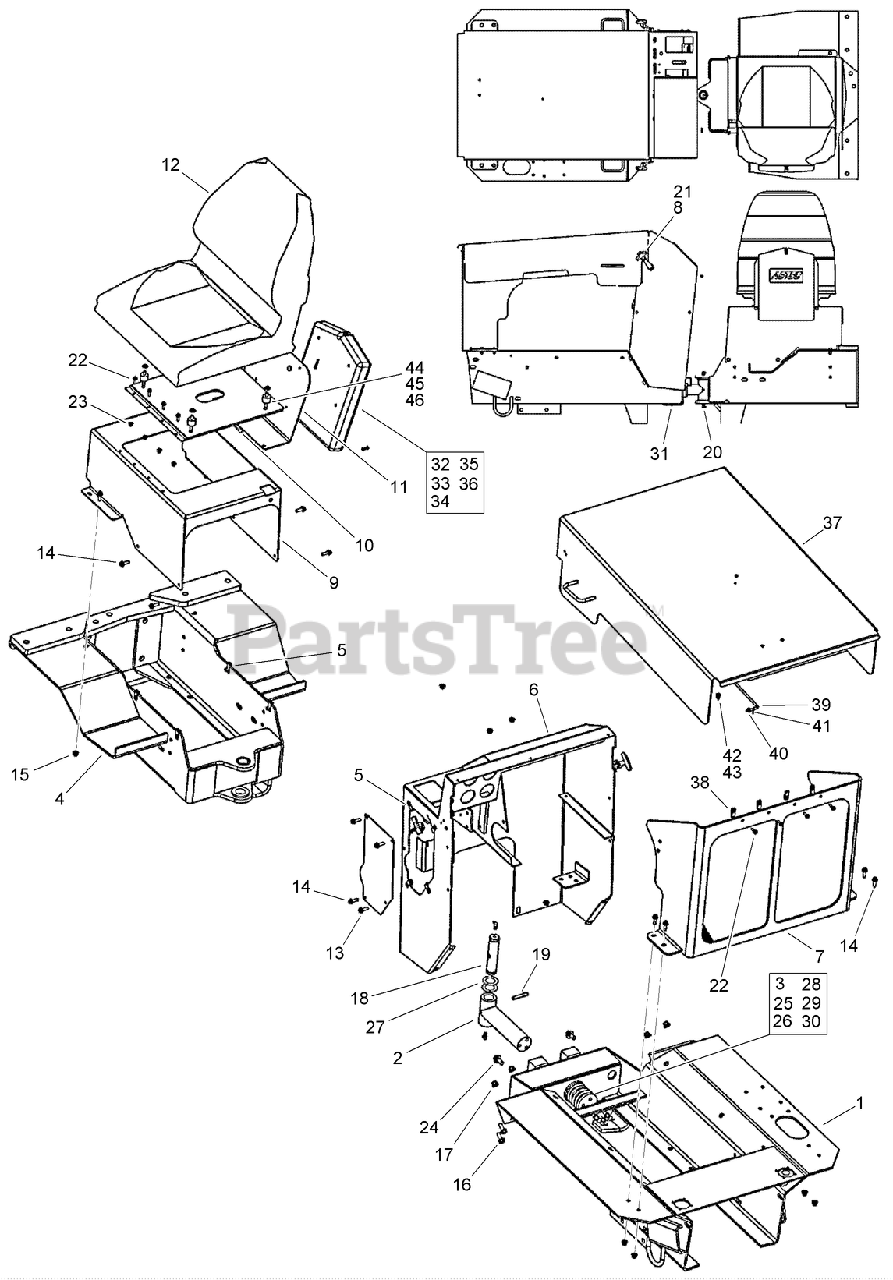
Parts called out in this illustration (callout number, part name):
1	FRAME - Front
2	PIVOT-ARTICULATION
4	FRAME - Rear
6	CONSOLE
7	WELDMENT - Grill/Hood Support
8	LATCH - Flexible Draw
9	SUPPORT - Seat
10	PLATE - Seat Mounting
11	PLATE - Mounting, Operators Manual
12	SEAT-NON SUSPENSION
13	PANEL - Cover
14	SCREW-HH
15	NUT-TORQUE, PREVAILING
16	SCREW-FLANGE
17	NUT-FLANGE, NYLOCK
18	PIN-PIVOT
19	PIN-SLOTTED, SPRING
20	FITTING-grease, 90 degree, 1/8 PT x 27/32 inch
21	RIVET - Blind Brk Mdrl .187 x .450 in ZND
22	SCREW-HHF
23	NUT, METRIC FLANGE PREVAILING - M6 Zinc
24	SCREW-HHF
25	WASHER-Spring Lock, Reg 3/8 ZND
26	SCREW-HH
29	SHIM-THIN
30	WIRE-STEEL
31	FITTING-GREASE
32	HOLDER-MANUAL, OPERATOR
33	LANYARD
35	STRAP-TIE, NYLON
36	POST-MANUAL
37	WELDMENT, Hood
39	PROP ROD - Hood
41	PIN - Cotter .094 x .75 in ZN
42	HOLDER-PROP, ROD
43	RIVET - Blind Brk Mdrl .125 x .400 in ZND
44	WASHER-FLAT
45	MOUNT-RADIATOR
46	NUT-Hex Serrated Flange, 5/16 inch NC
